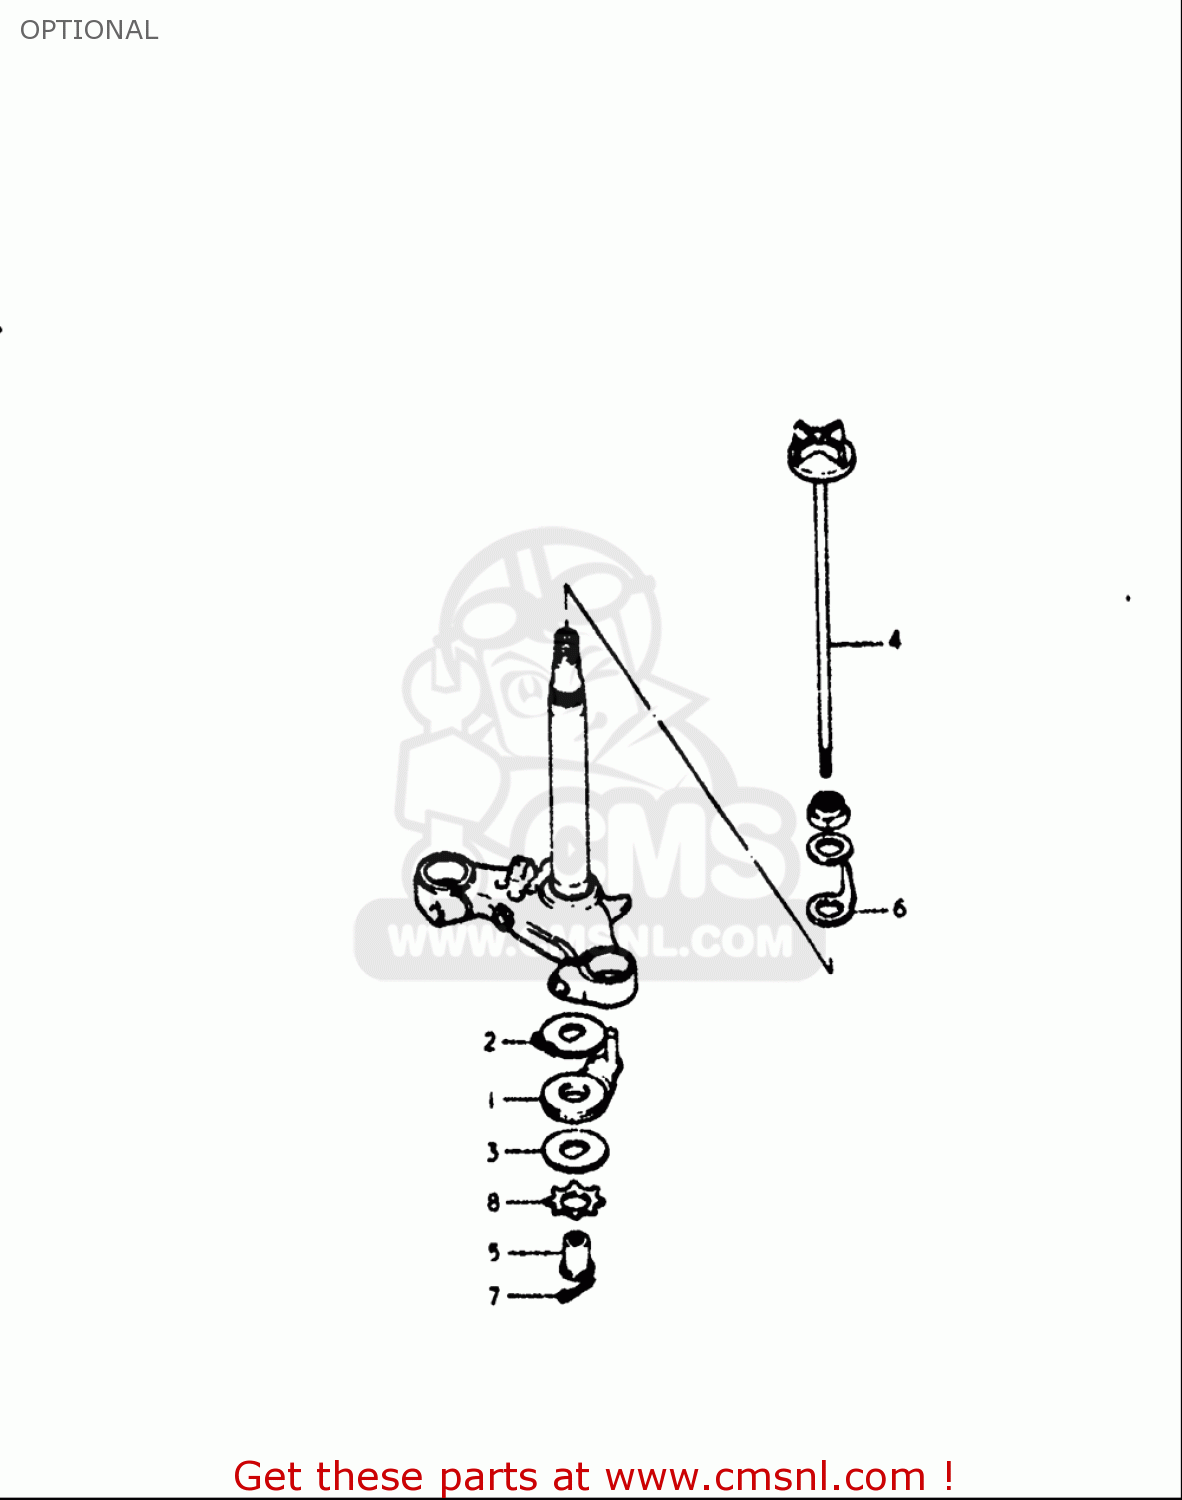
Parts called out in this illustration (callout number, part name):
5	HUB,HANDLEBAR DAMPER S
7	CLIP
8	SPRING, DAMPER ADJUST
